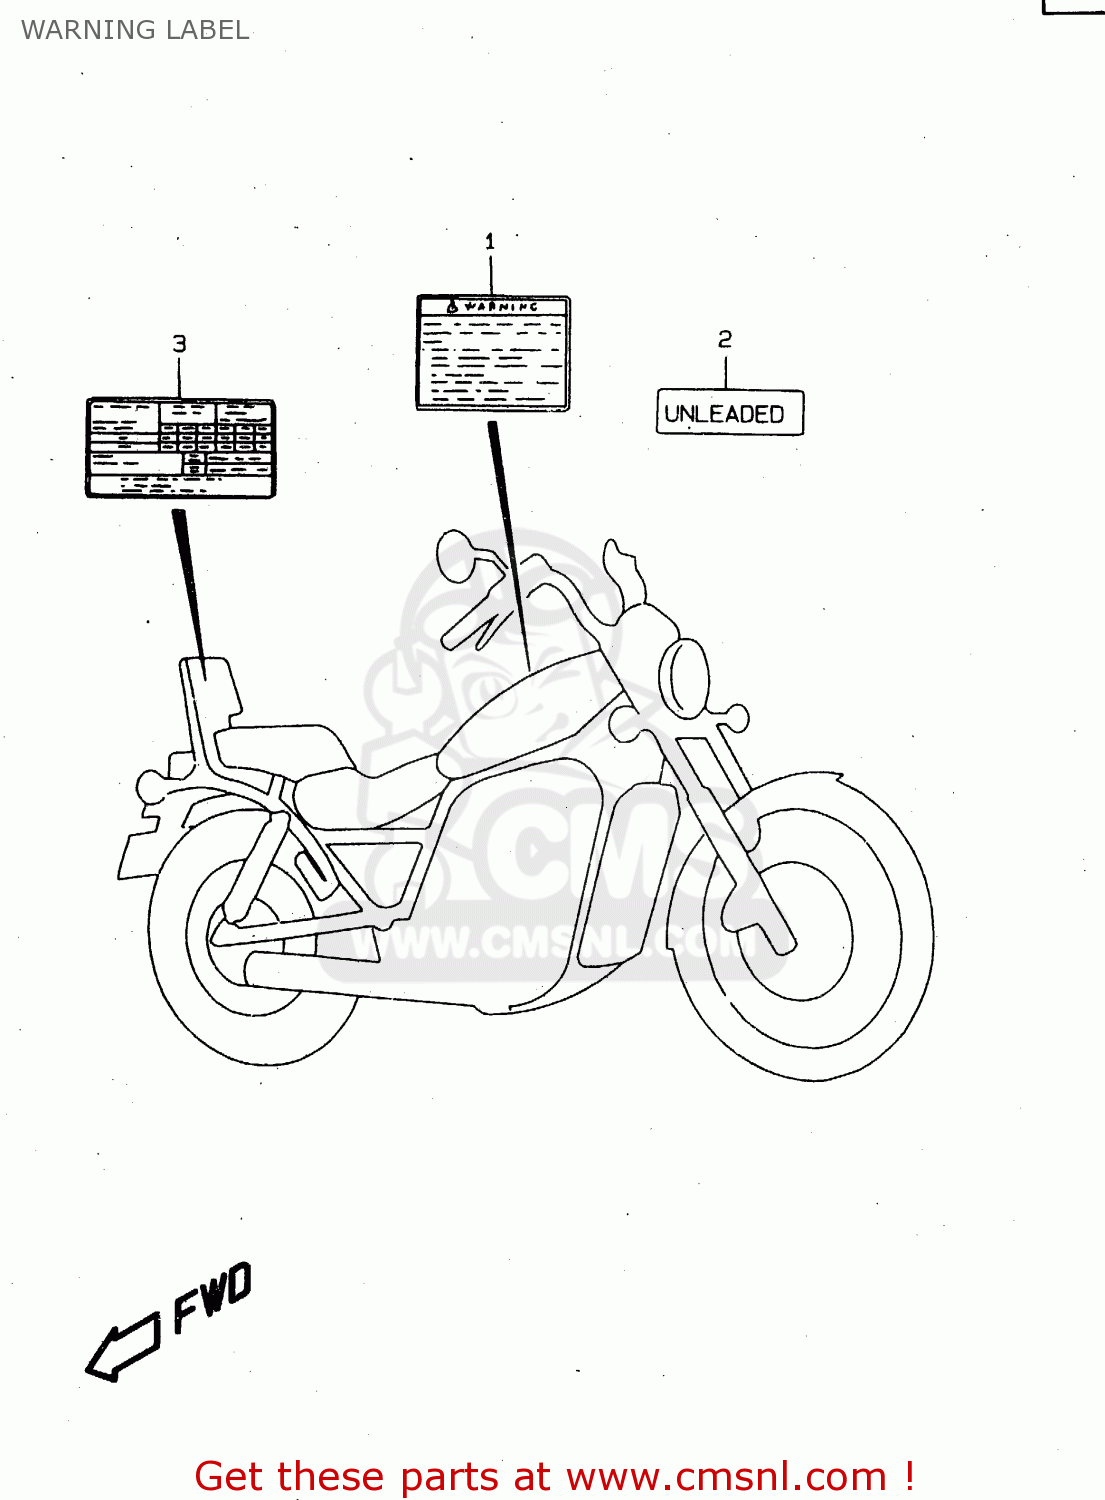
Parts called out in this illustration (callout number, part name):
1	LABEL,WARNING
2	LABEL,CAUTION
3	LABEL, AIR INFORMATION
4	MANUAL, OWNER'S
